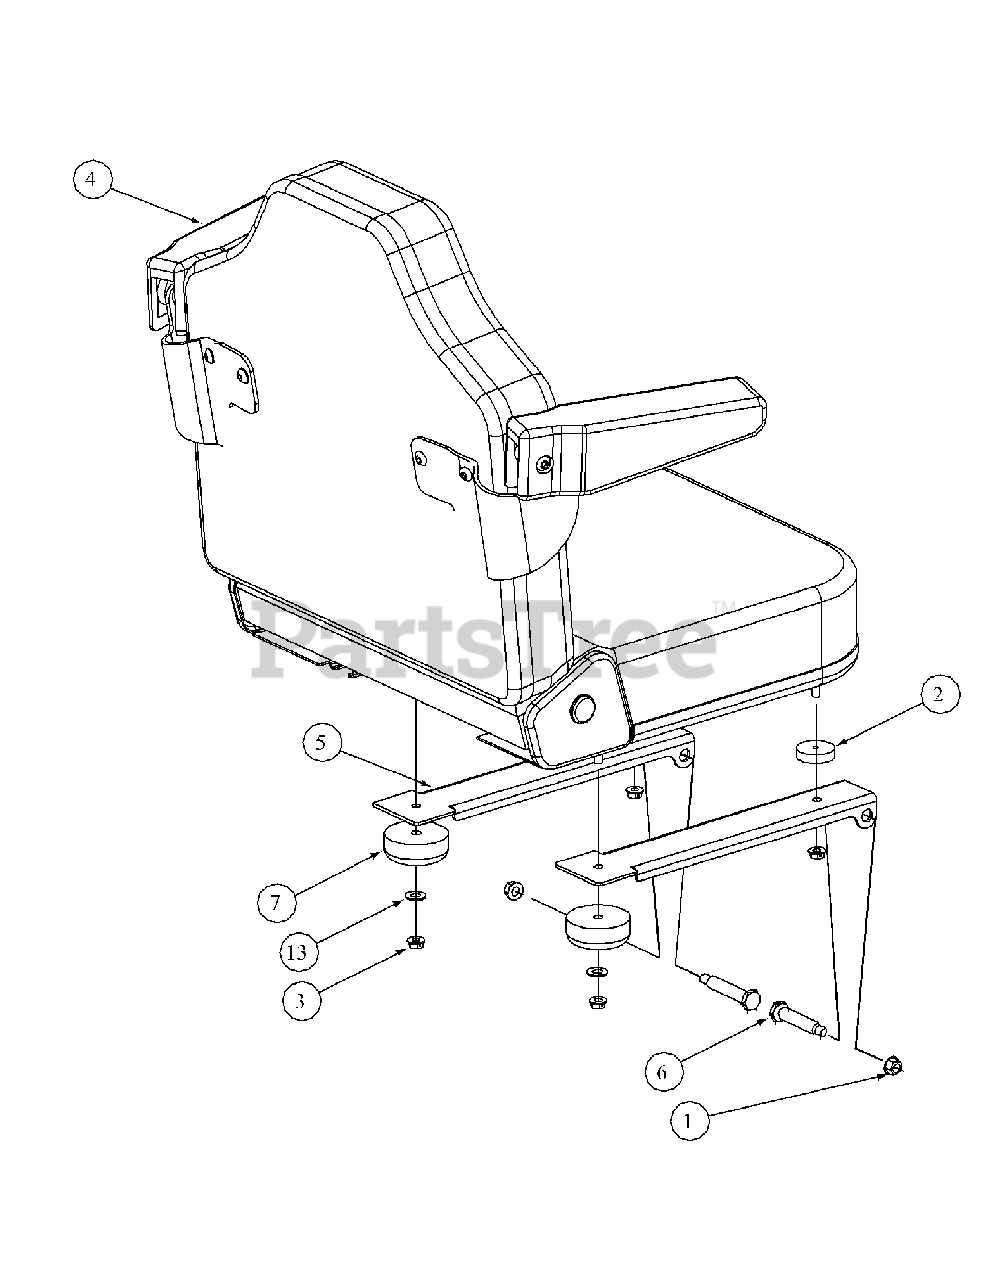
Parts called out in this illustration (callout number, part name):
1	Nut, Hex 3/8-16 Flange Lock
2	Spacer, 0.345 ID x 1.50 OD x .41
3	Lock Nut, Hex Flange, 5/16-18
4	Adjustable Seat, Black embossed, forward fold
5	Mounting Bracket, Seat
6	Shoulder Screw, .50x2.345, 3/8-16
7	Grommet, 2.5 OD x 1.0 Long
13	Washer
